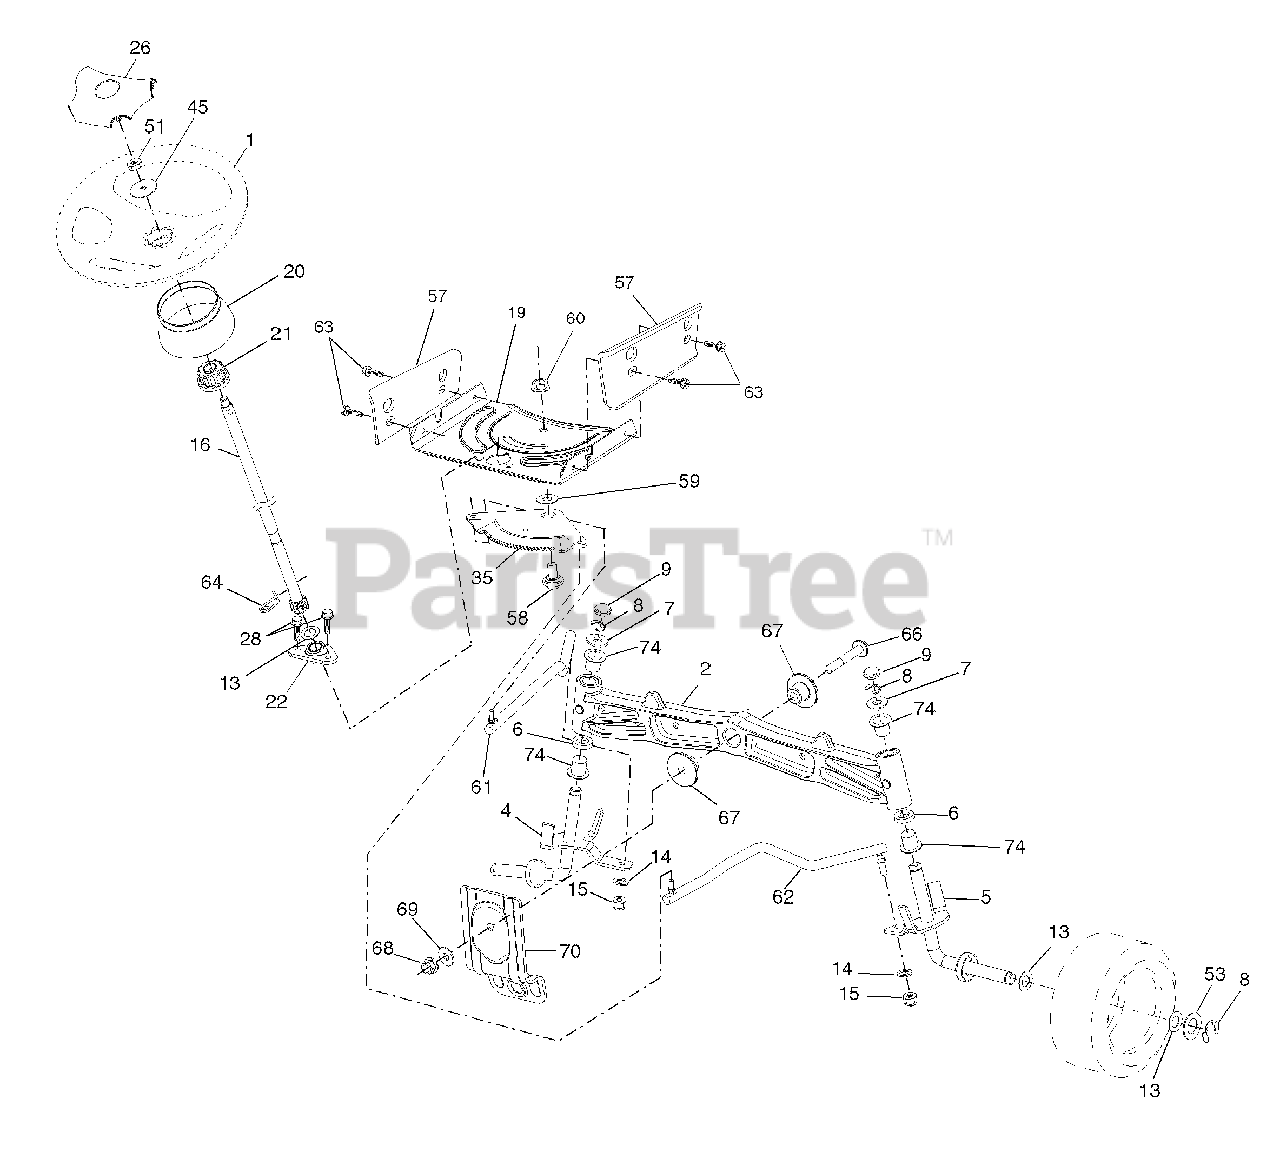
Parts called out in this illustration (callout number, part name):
1	Wheel, Steering
2	Axle Asm., Front
4	Spindle Asm., LH
5	Spindle Asm., RH
6	Bearing, Race Thrust Harden
7	Washer 25/32 x 1-5/8 x 16 Ga.
8	Ring, Klip #T5304-75
9	Cap, Spindle
13	Washer 25/32 x 1-1/4 x 16 Ga.
14	Washer, Lock Hvy Hlcl Spr 3/8
15	Nut, Crown Lock 3/8-24 unf
16	Shaft Steering
19	Plate Steering
21	Adapter, Wheel Steering
22	Bushing, Strg. Blk
26	Insert, Wheel Steering
28	Screw 3/8-16 x 3/4
35	Gear, Sector Plate
45	Washer 9/16 ID x 2-3/8 OD 12 Ga.
51	Nut Hex Jam Toplock 1/2-20 unf
53	Washer Hardened .793 x 1.637 x .060
57	Bracket Upstop
58	Bolt Shoulder Sector Pivot CFM
59	Washer Thrust Sector Steering
60	Nut Flange Lock 5/8-11
61	Draglink LH
62	Draglink, RH
63	Screw 5/16-18 x 3/4
64	Retainer Clip Spring Steering
66	Bolt Hex Fghd 7/16-14 x 3 Serr
67	Bushing PM Front Axle
68	Nut Lock Flange 7/16-14 Gr. 5
69	Washer 1.5 x .505 x .118
70	Bracket Deck Susp. Front
74	Bearing
